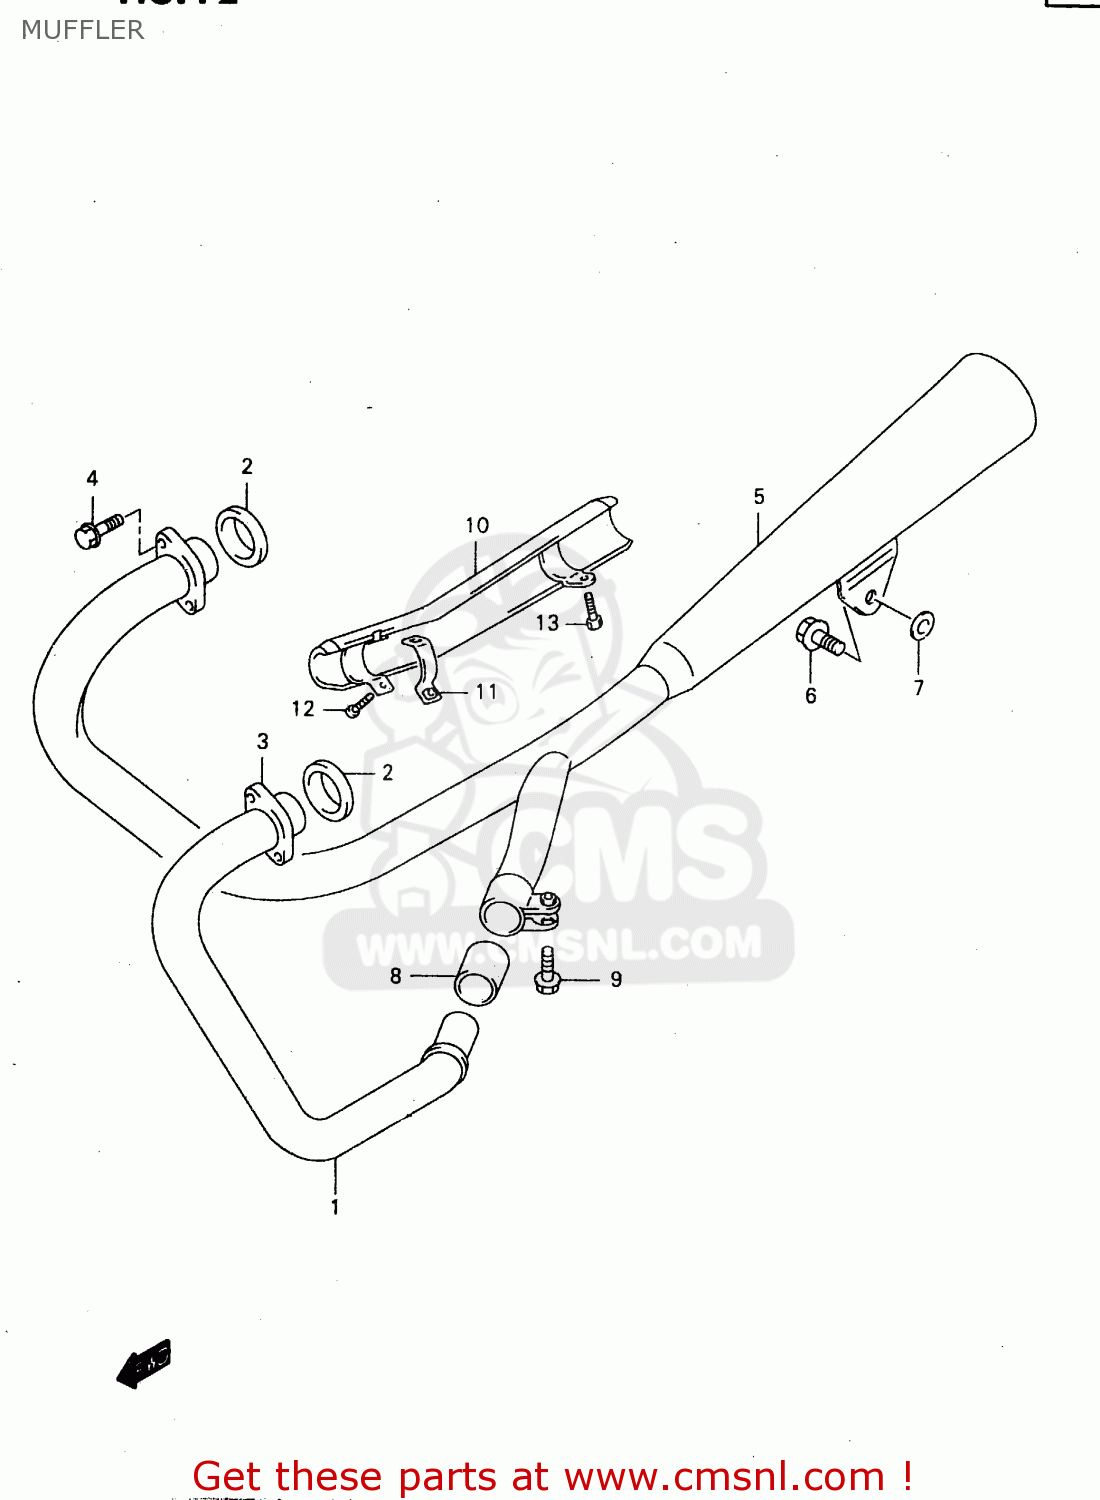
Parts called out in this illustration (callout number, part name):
1	PIPE,EXHAUST,L
2	GASKET,EXHAUST PIPE (NAS)
3	CLAMP,EXHAUST PIPE,L
4	BOLT(6X25)
5	MUFFLER
6	BOLT
7	WASHER
8	CONNECTOR,MUFFLER
9	BOLT
10	COVER COMP,MUFFLER
11	CLAMP,MUFFLER COVER
12	SCREW
13	SCREW
